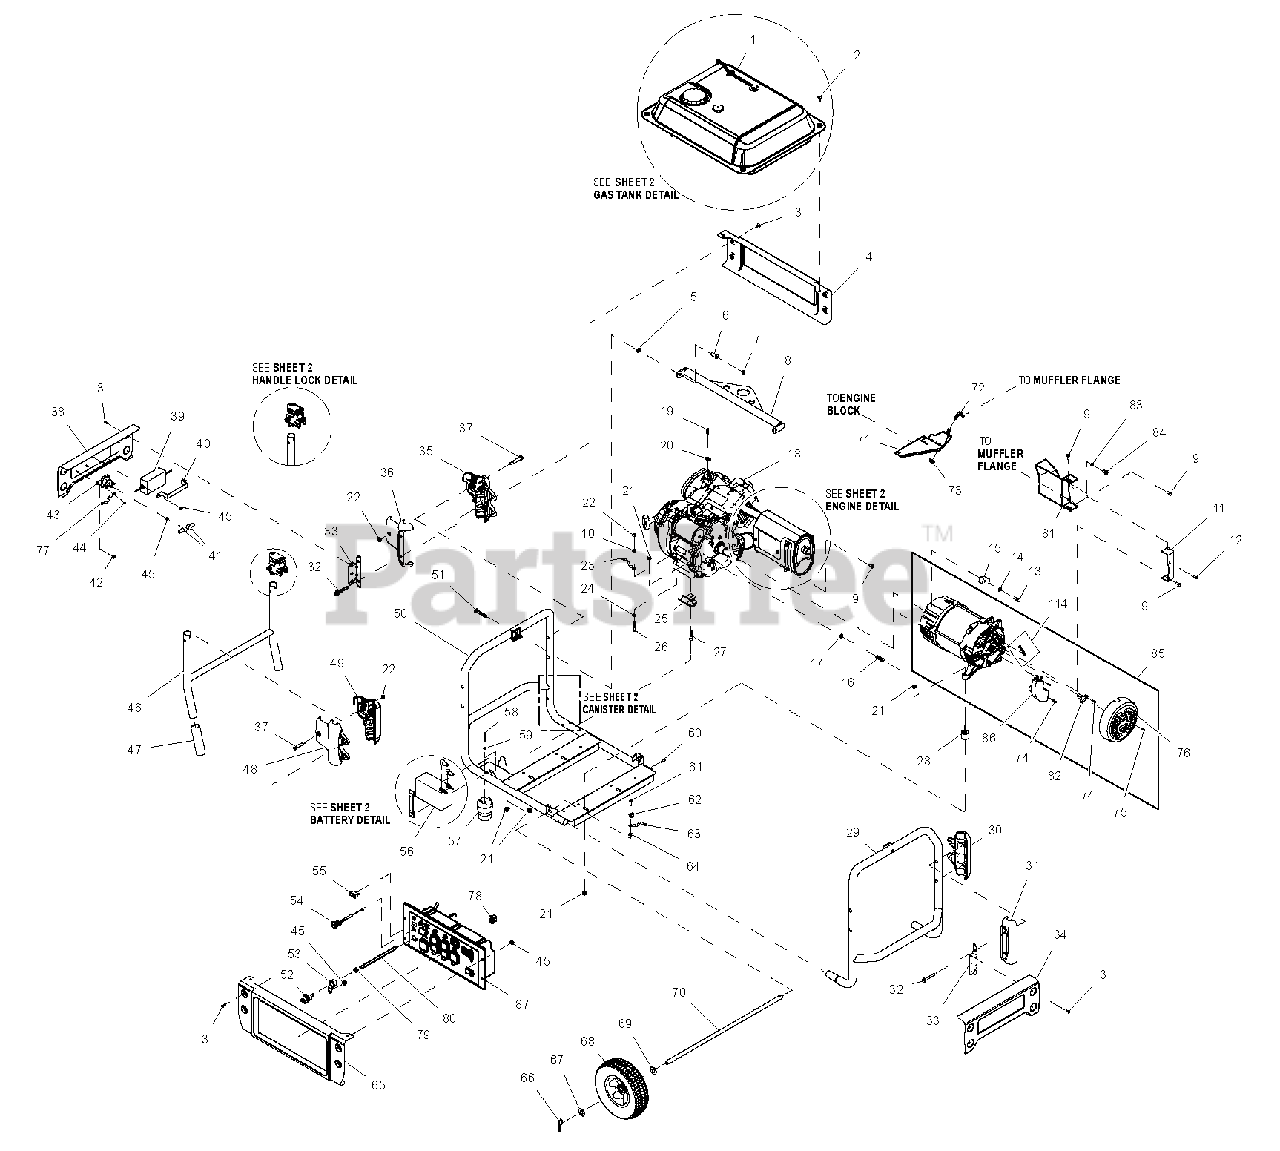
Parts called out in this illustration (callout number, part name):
1	ASSY FUEL TANK 9 GAL XP CARB
2	SCREW TTH M8-1.25 X 20
3	SCREW SWT 1/4-20 X 5/8 W/W
4	PANEL SIDE XP
5	WASHER NYLON .50 X .87 X .06
6	BUSHING'FLANGED HEAD
7	NUT HEX LOCK M8-1.25 NY INS
8	ASSY LIFTING BEAM XP6.5-8
9	SCREW SHC M8-1.25 X 20 SEMS
10	WASHER FLAT M8 SS
11	WLDMNT MTG MUFFLER ALT SIDE
12	SCREW HHFC M6-1X25 8.8 W/PATCH
13	SCREW HHC 5/16-24 X 1-1/4 G5
14	WASHER LOCK M8-5/16
15	BRACKET' MOUNTING' ALT 7KW
16	SCREW HHC 3/8-16 X 1-1/4 G5
17	WASHER LOCK M10
18	ASSY ENGINE 410 XP CARB
19	SCREW HHC SHLDR M5-0.8X20 G8.8
20	CLAMP' 3/16" COATED CABLE
21	NUT HEX FL WHIZ M8-1.25
22	NUT HEX M8-1.25 G8 CLEAR ZINC
23	WIRE ASSY FRAME TO BATT-NEG
24	WASHER LOCK M8 SS
25	VIBRATION MNT 45 ANGLE 65 DURO
26	SCREW HHC M8-1.25 X 40 C8.8
27	SCREW SHC M8-1.25 X 40 C8.8
28	VIB MNT 25 X 31.8 X M8-1.25
29	WELD CRADLE ALT END
30	CORNER SUPPORT - OUTER XP PORT
31	CORNER SUPPORT - INNER XP PORT
32	SCREW HHFC M8-1.25X60 C8.8 ZP
33	BRACKET END PANEL
34	PANEL END XP
35	CORNER HANDLE SUPT-LFT INNER
36	CORNER HANDLE SUPT-LFT OUTER
37	SCREW SHSH M8-1.25 X 40
38	WELD END PANEL XP
39	BATTERY CHARGER 13.4VDC 2.5A
40	BRKT HOLD DOWN BATT CHRGR
41	BOOT' VINYL STARTER-SOLENOID
42	NUT HEX LOCK 1/4-20 NY INS
43	CONTACTOR' STARTER SOLENOID
44	NUT HEX LOCK #8-32 NY INS BRS
45	NUT HEX FL WHIZ M6-1.0
46	WELD HDL H-STYLE FOLD DOWN
47	GRIP HANDLE FOAM
48	CORNER HANDLE SUPT-RT OUTER
49	CORNER HANDLE SUPT-RT INNER
50	WELD CRADLE ENGINE END
51	CURVED HEAD M8-1.25 X 42MM LNG
52	VALVE' FUEL SHUT OFF
53	MTG FUEL VALVE RETAINER
54	CABLE CHOKE PORT NOM 465
55	SWITCH SPDT (ON)-OFF-ON 20A
56	BATTERY 12V10AH SEALED
57	ASSY FOOT
58	SCREW HHC M6-1.0 X 45 C8.8 FTH
59	WASHER FLAT M6 SS
60	SCREW HHSD 1/4-14 X 7/8 BZ
61	SCREW HHTT M6-1.0 X 25 ZINC
62	LUG SLDLSS #2-#8 X 17/64 CU
63	GRND WIRE PORT BRG CARR-FRAME
64	WASHER LOCK SPECIAL 1/4"
65	WELD PANEL SIDE C-PNL XP
66	COTTER HAIRPIN 2.56 X .80
67	WASHER FLAT 5/8 ID X 0.039"THK
68	WHEEL 10"DIA' OFFSET HUB
69	WASHER FLAT 5/8 ZINC
70	AXLE 16MM DIA X 681 CLR ZINC
71	WLDMNT SUPPORT MUFFLER
72	J-BOLT MUFFLER M8-1.25
73	NUT TOP LOCK FL M8-1.25
74	SCREW HHFC M5-0.8 X 16
75	SCREW HHFC M5-0.8 X 12
76	COVER ALTERNATOR INLET 5-7KW
77	WIRE' JUMPER'SOL COIL-CONTACT
78	CLIP SNAP-IN WIRE MANAGEMENT
79	CLAMP HOSE BAND .41
80	FUEL HOSE' 160 MM LONG
81	WLDMNT MTG MUFFLER SIDE
82	BRUSH ASSY
83	WASHER FLAT M8
84	SCREW HHC M8-1.25 X 16 C8.8
